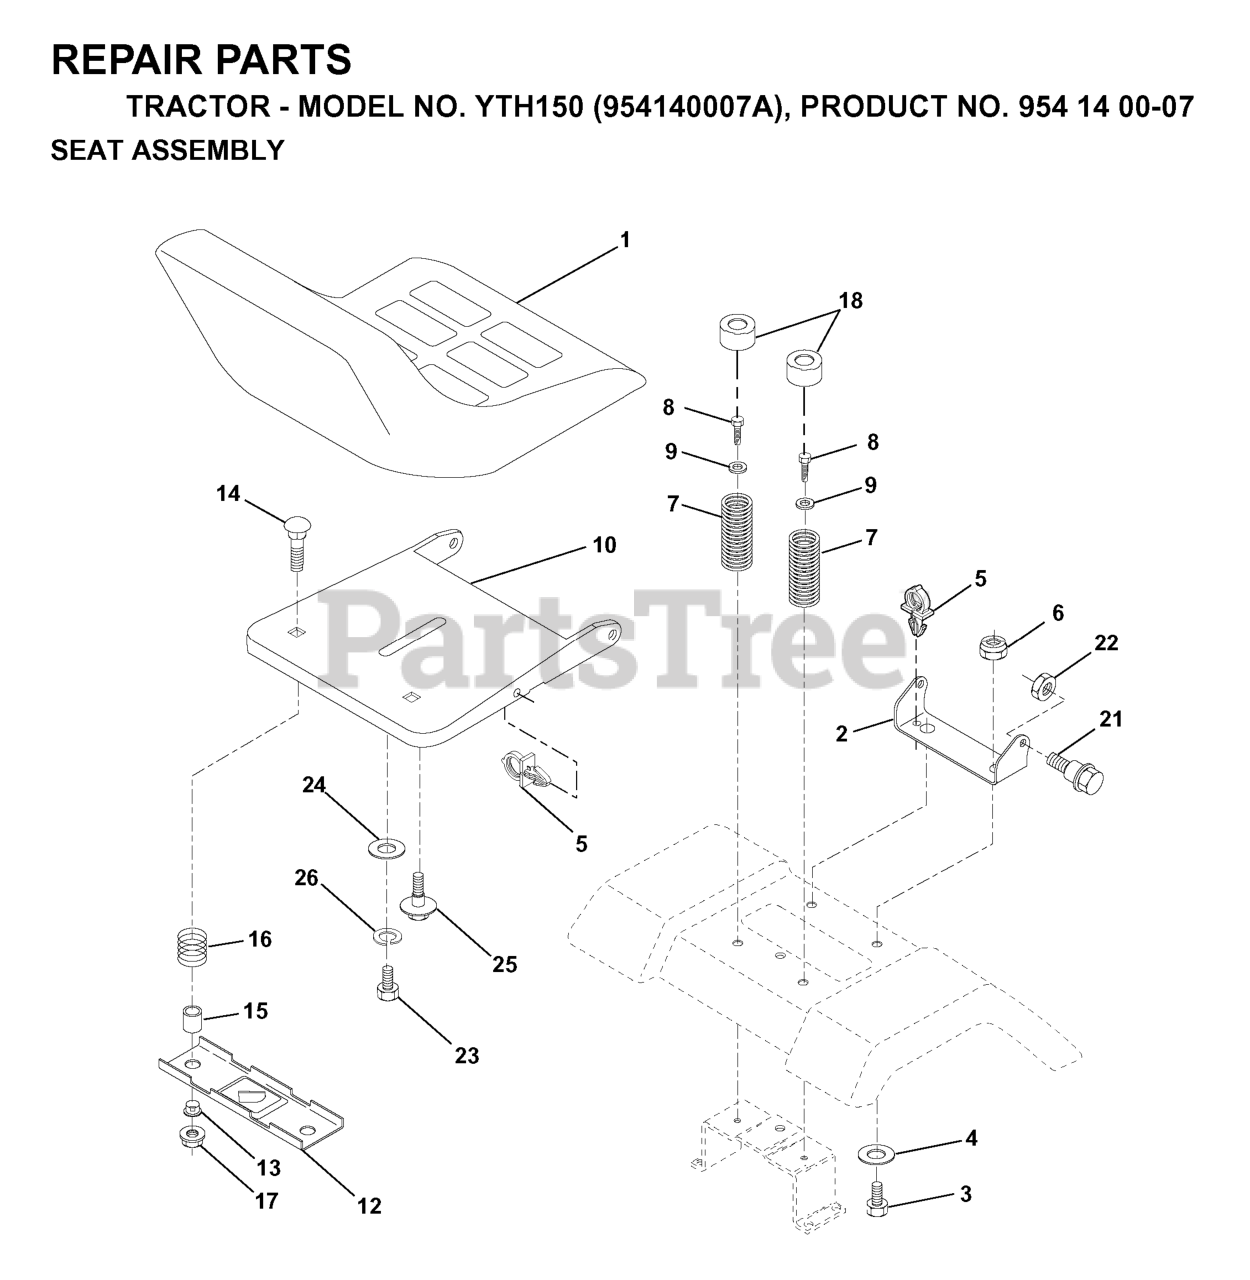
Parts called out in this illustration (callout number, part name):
1	SEAT, GRAY
2	SEAT PIVOT BRKT
3	BOLT
6	NUT
7	SPRING COMPRESSION
8	SCREW GTV
9	WASHER
10	PAN, SEAT
12	BRKT SWITCH
14	Bolt Rdhd. Sht. Nk 1/4-20 x 1-3/8
15	SPACER SPLIT 28X.96
17	NUT T
18	CAP SPRING
21	BOLT SHOULDER 5/16-18
22	NUT.71038.31-18.HEX.NYLOCK
23	BOLT
25	BOLT,SHOULD
26	LOCKWASHER
